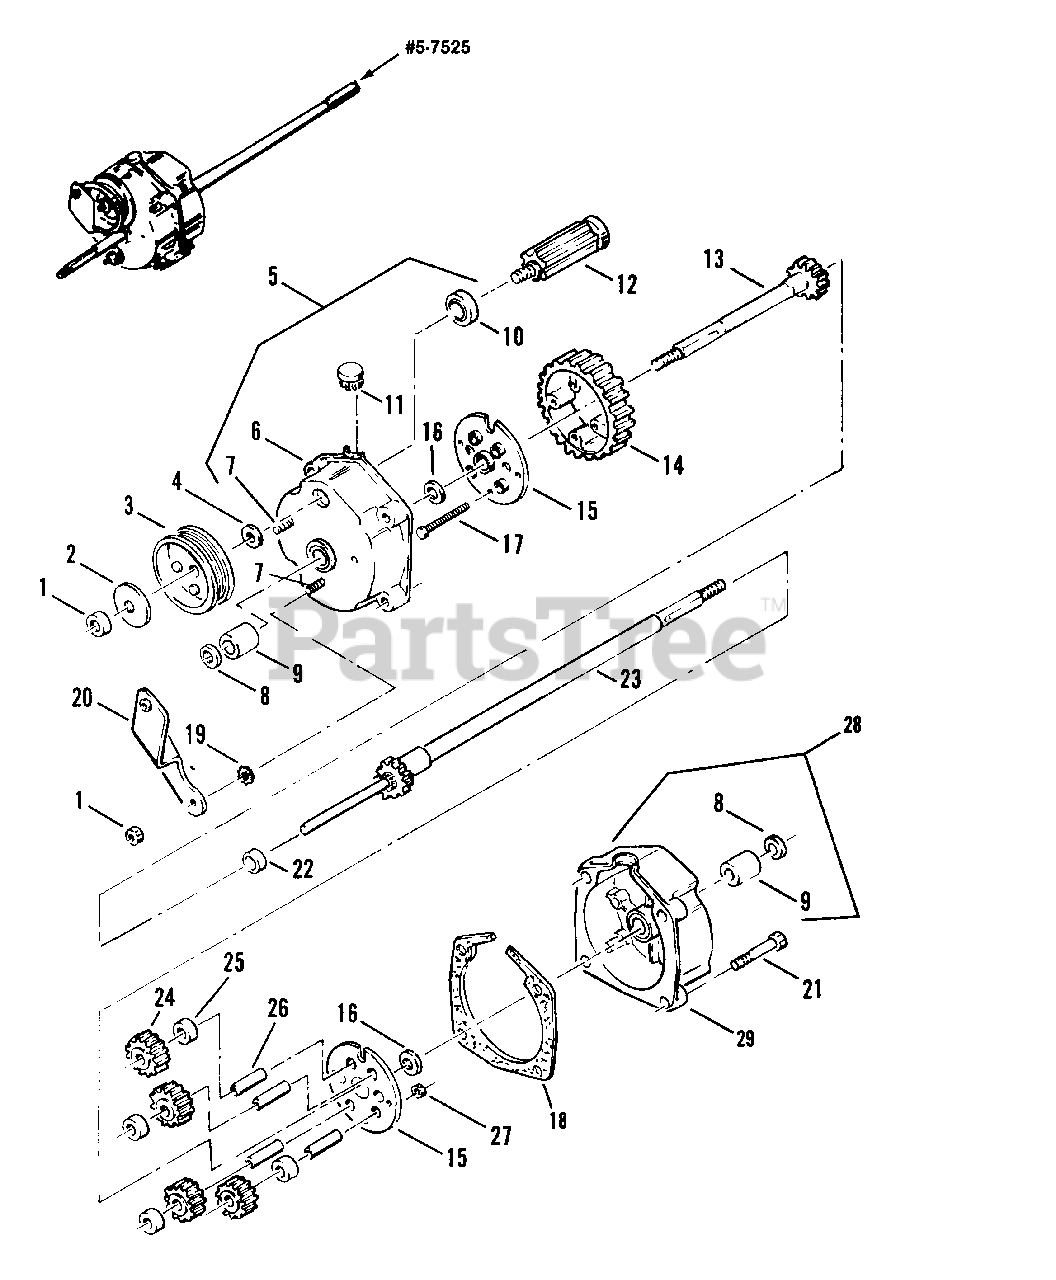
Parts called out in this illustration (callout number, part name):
1	NUT, 5/16-24 Hex Lock, GR C
2	WASHER, Spring
3	PULLEY, Poly-Vee Belt
4	WASHER, Spring
5	HOUSING ASSEMBLY, Right
6	HOUSING, Right Side
7	SCREW, 5/16-24 x 1-1/8" Rib Neck
8	SEAL, 5/8" ID
9	BEARING, Differential
10	BEARING, Ball
11	PLUG, Housing
12	GEAR, Input
13	AXLE, Short
14	GEAR, Differential, 46 Tooth
15	PLATE
16	WASHER, Thrust
17	SCREW, Cap, 10-32 x 1-1/2"
18	GASKET, Housing
19	WASHER, 5/16" Internal External Tooth Lock
20	BRACKET, Differential
21	SCREW, 1/4-20 x 1-1/4 Self-Tapping
22	SPACER, Axle Gear
23	AXLE, Long
24	GEAR, Pinion, 12 Tooth
25	SPACER, Pinion Gear
26	SHAFT, Pinion
27	LOCKNUT, 10-32
28	HOUSING ASSEMBLY, Left
29	HOUSING, Left Side
